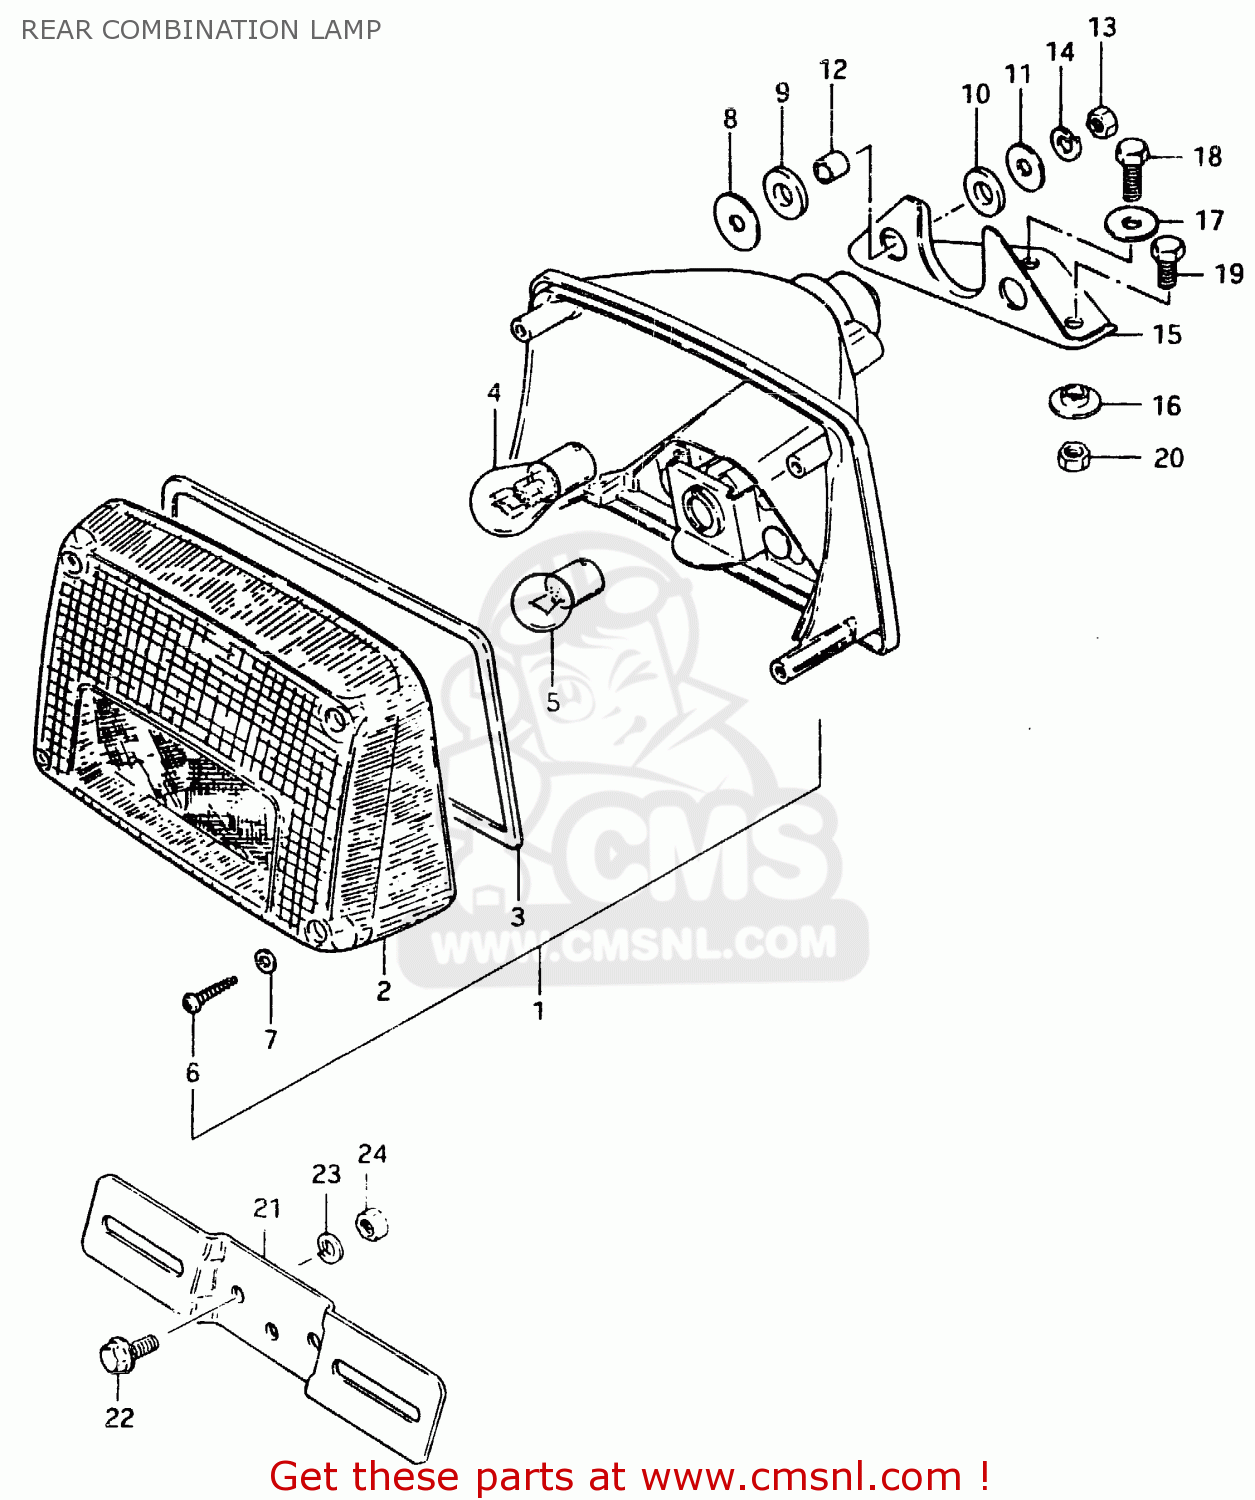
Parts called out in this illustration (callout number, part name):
1	LAMP ASSEMBLY,REAR COMBINATION
2	LENS
3	GASKET (NAS)
4	BULB(12V23W)
5	BULB
6	SCREW,REAR COMBINATION LAMP
7	GASKET (NAS)
8	WASHER
9	CUSHION
10	CUSHION
11	WASHER(6,5X22X1.6)
12	SPACER(6.1X9X7.5)
13	NUT
14	LOCK WASHER
15	BRACKET,RR COMBINATION LAMP
16	WASHER
17	WASHER
18	BOLT
19	BOLT, UPPER
20	NUT 6MM
21	BRACKET, LICENSE PLATE
22	BOLT
23	LOCK WASHER
24	NUT
